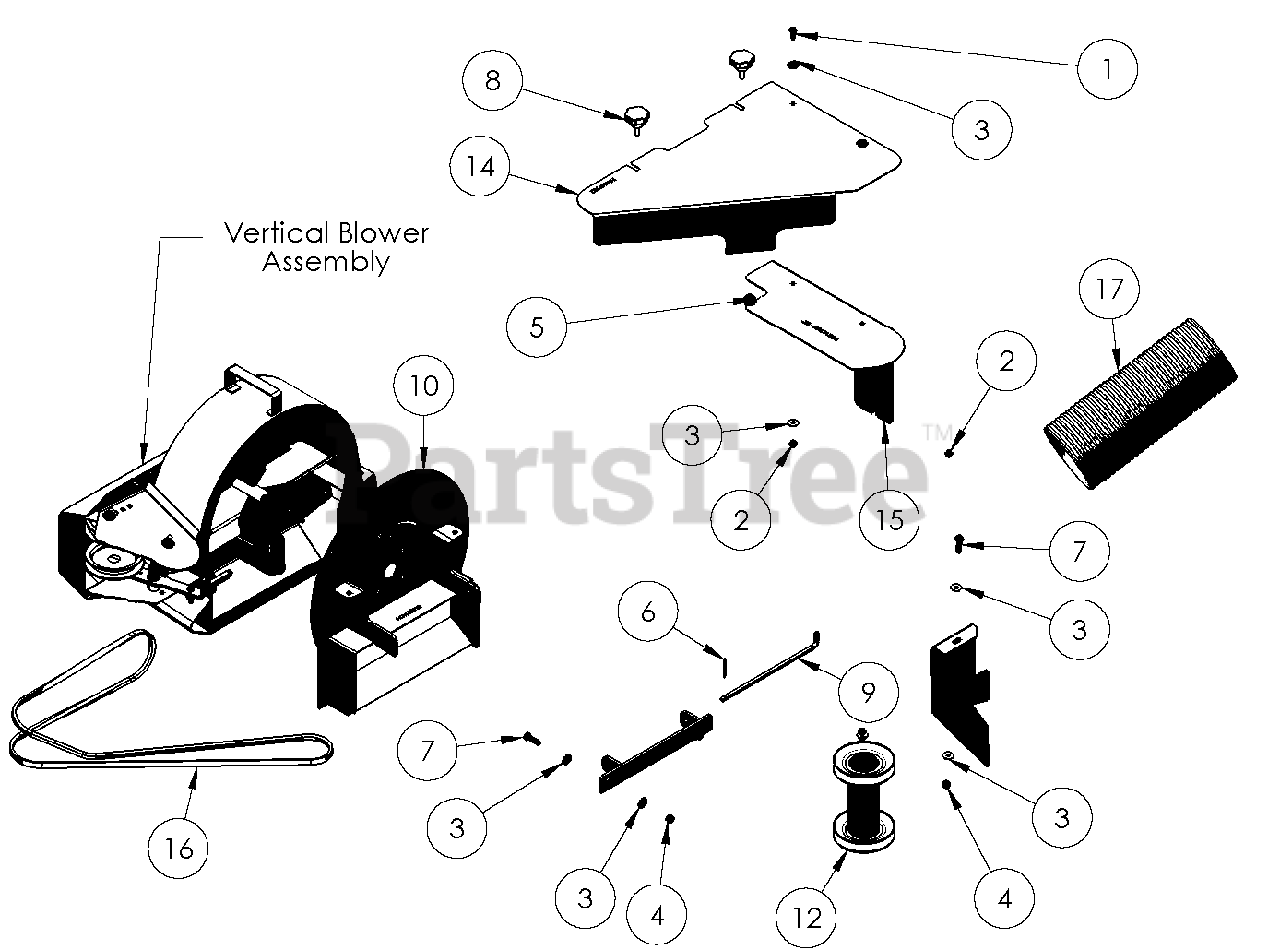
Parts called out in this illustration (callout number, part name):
1	Cap Screw 5/16- 18 X .75
2	5/16- 18 Nylon Insert Nut
3	5/16" Flat Washer
4	3/8- 16 Nylon Insert Nut
5	Rubber Bumper
6	Hair Pin, 0.091 X 1.875
7	Cap Screw 3/8- 16 X 1 1/4 Lg
8	Release Knob
9	Mounting Pin, 'L' 10.25" EL
10	Blower Mount, Pro Series
11	Deck Bracket, 66" Pro Series
12	Double Pulley, Pro Series
13	Deck Seal, 66" Pro Series
14	Front Pulley Cover, PRO Series 60-66
15	Pulley Cover Leg, 66" Pro Series
16	Belt, Aramid Cord 103"
17	Hose, 6" X 48" Lg.
